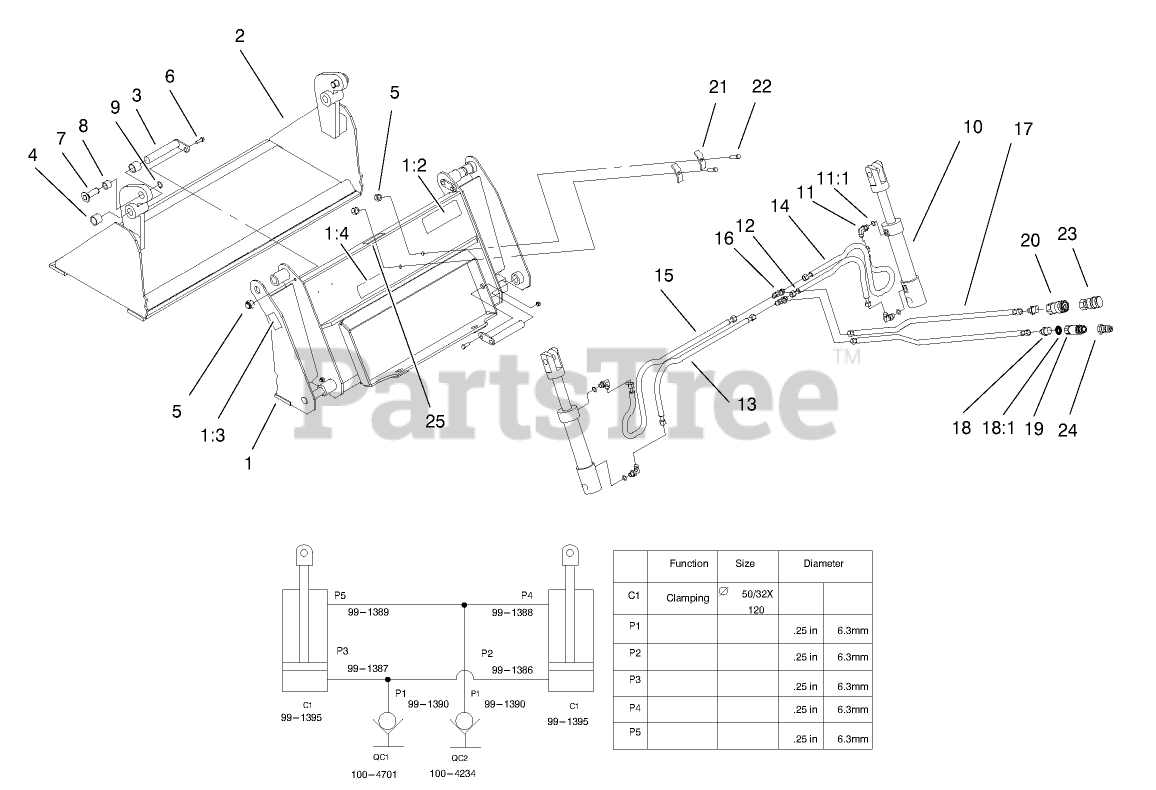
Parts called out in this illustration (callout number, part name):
1	Base ASM
1:2	DECAL-WARNING
1:3	DECAL-WARNING
1:4	DECAL-LOAD RATING
4	BUSHING
5	NUT-LOCK, NI
6	SCREW-HHF
8	BUSHING
9	Ring-Snap
10	CYLINDER - HYDRAULIC
11	FITTING-ELBOW, 90 DEG
11:1	O-RING
12	HOSE ASM-HYDRAULIC
13	HOSE ASM-HYDRAULIC
14	HOSE ASM-HYDRAULIC
15	HOSE ASM-HYDRAULIC
16	ADAPTER - TEE
17	HOSE ASM-HYDRAULIC
18	ADAPTER-HYD
18:1	O-RING
19	NIPPLE-CONNECT, PRESSURE
20	COUPLER-FACE, FLUSH
21	CLAMP - HOSE
22	SCREW-HHF
23	DISCONNECT-QUICK, FEMALE
24	DISCONNECT-QUICK, MALE
25	DECAL-ATTACHMENT, DINGO
